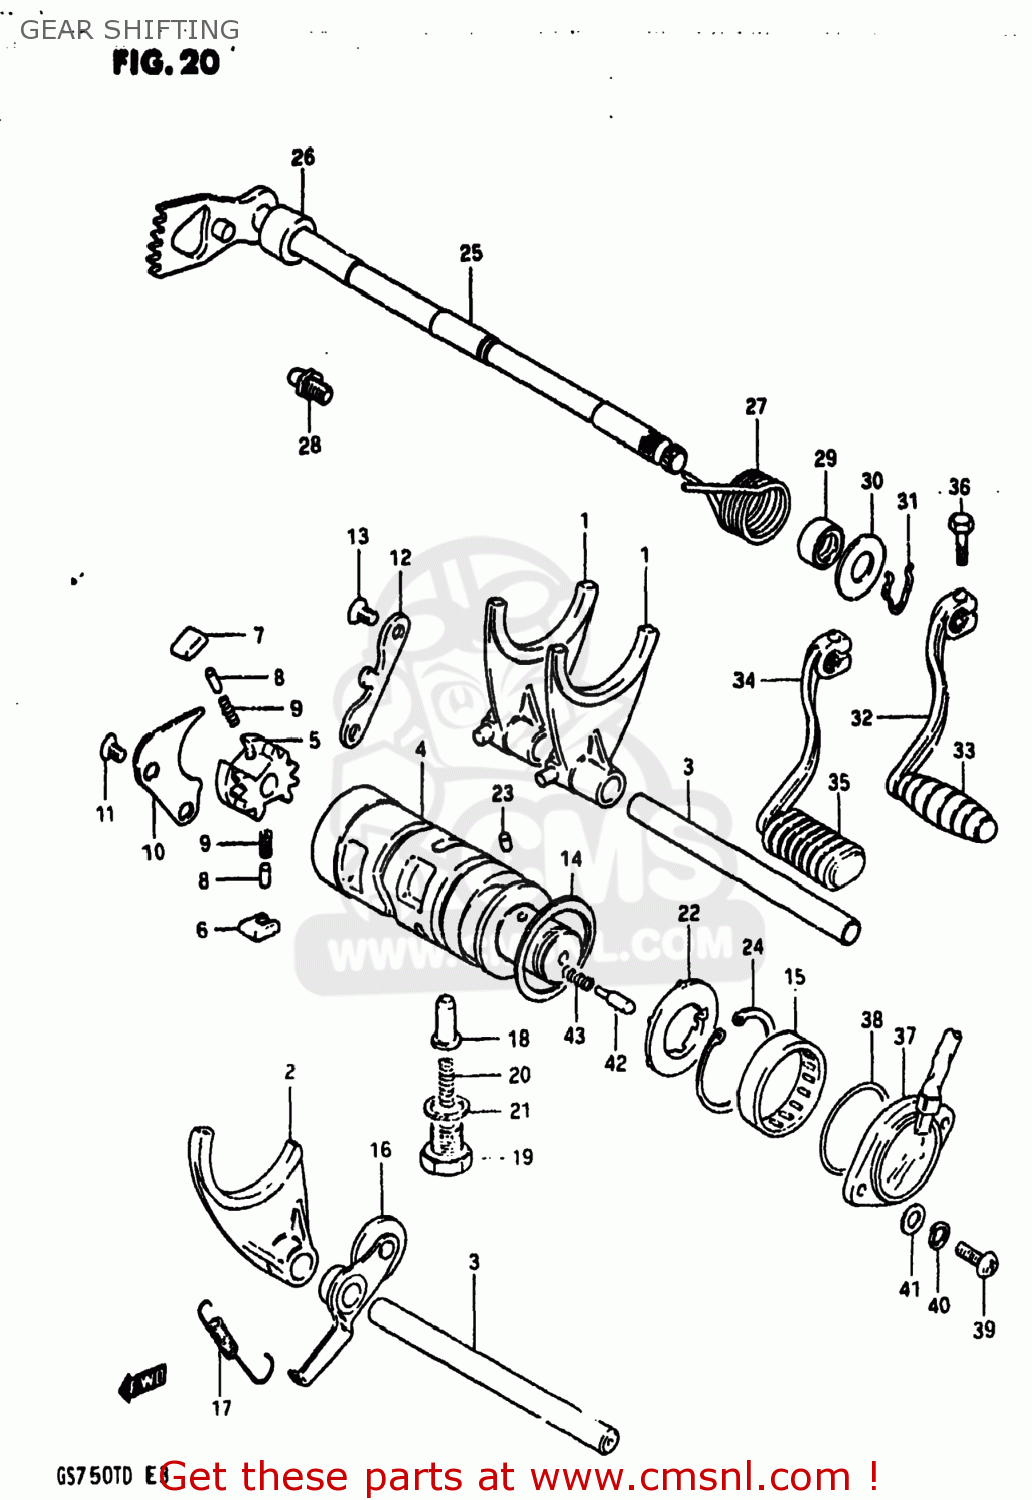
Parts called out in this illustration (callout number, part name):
1	FORK,GEAR SHIFT NO.1
2	FORK,GEAR SHIFT NO.3
3	SHAFT,GEAR SHIFT FORK
4	CAM,GEAR SHIFT
5	RETAINER,GEAR SHIFT CAM
6	PAWL,GEAR SHIFT NO.1
7	PAWL,GEAR SHIFT NO.2
8	PIN(5X8)
9	SPRING
10	LIFTER,GEAR SHIFT PAWL
11	SCREW
12	GUIDE,GEAR SHIFT CAM
13	SCREW
14	WASHER(40X45X1)
15	BEARING(25X32X12)
16	STOPPER,GEAR SHIFTING
17	SPRING
18	STOPPER,GEAR SHIFT CAM NO.2
19	HOLDER,GEAR SHIFT CAM STOP SPR
20	SPRING
21	GASKET(14X19.2X2) (NAS)
22	PLATE,GEAR SHIFT CAM STOPPER
23	PIN 4X6
24	CIRCLIP,25MM
25	SHAFT,GEAR SHIFT
26	SPACER(12X20X15.3)
27	SPRING
28	STOPPER,GEAR SHIFT CAM
29	OIL SEAL
30	WASHER (12.5X27X1.6)
31	SPRING,RETAINER
32	LEVER ASSY,GEAR SHIFT
33	RUBBER,GEAR SHIFT PEDAL
34	LEVER ASSEMBLY,GEAR SHIFTING
35	RUBBER,PEDAL
36	BOLT
37	TERMINAL BASE ASSY,GEAR SHIFT
38	O-RING (D:2.4 ID:26.2)
39	SCREW 5X20
40	LOCK WASHER
41	WASHER
42	PIN(5X15.5)
43	SPRING
